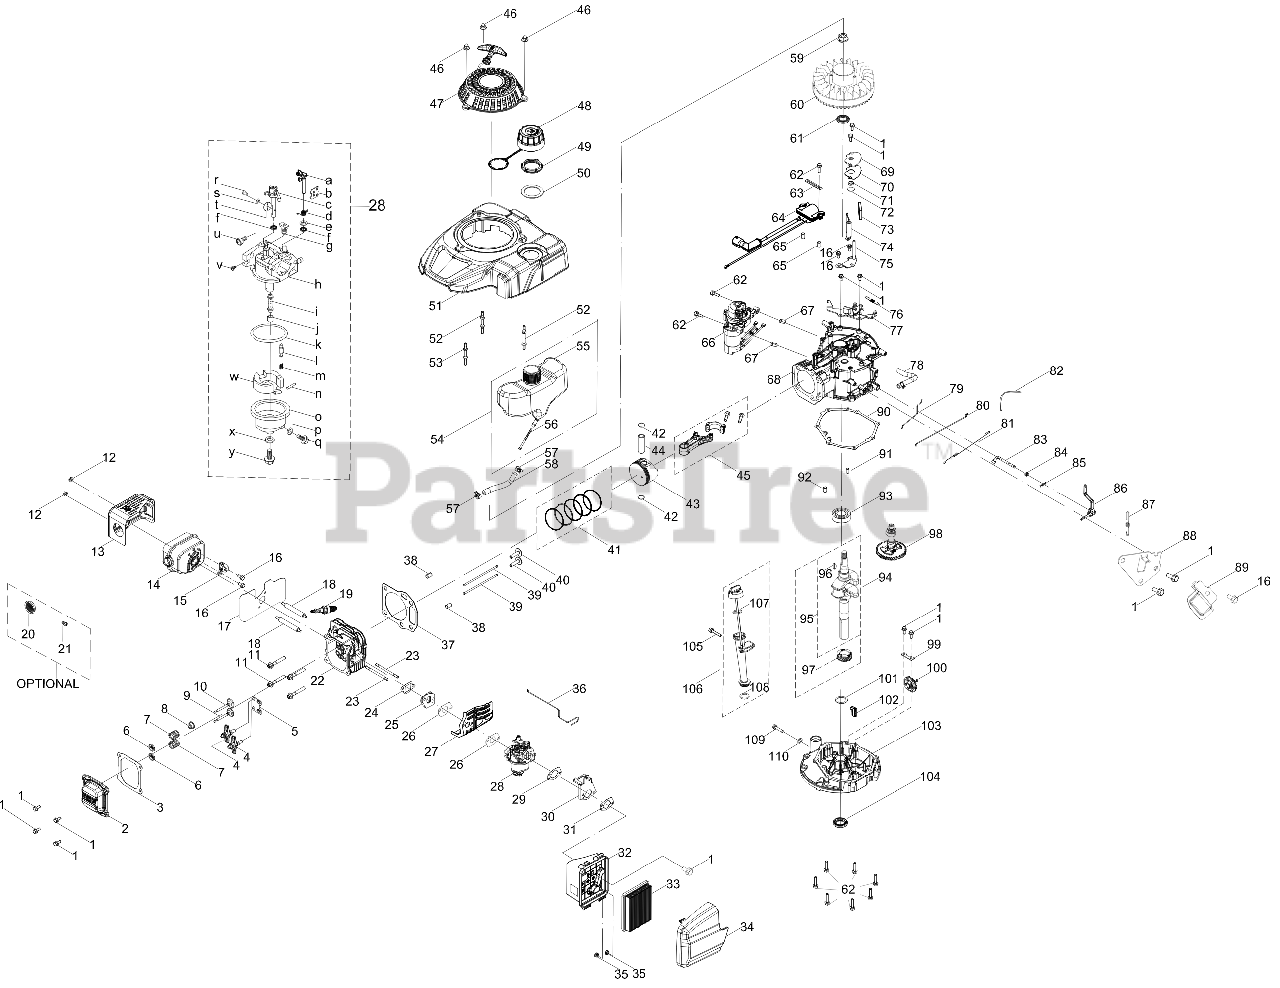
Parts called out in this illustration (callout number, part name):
1	BOLT M6-1 x 14 GR8.8
2	VALVE COVER
3	VALVE COVER GASKET
4	ROCKER ARM ASSEMBLY
5	PUSH ROD GUIDE
6	VALVE SPRING RETAINER
7	VALVE SPRING
8	INTAKE VALVE SEAL
9	EXHAUST VALVE
10	INTAKE VALVE
11	BOLT-M8 x 54
12	HEX NUT
13	MUFFLER SHIELD
14	MUFFLER ASSEMBLY
15	THERMOSTAT
16	BOLT M6-1 x 12 GR8.8
17	MUFFLER GASKET
18	STUD M6-1 x 95
19	SPARK PLUG
20	SPARK ARRESTOR
21	SCREW M3.5 x 9.5
22	CYLINDER HEAD
23	STUD M6 x 90
24	CARBURETOR INSULATOR GASKET
25	CARBURETOR INSULATOR
26	CARBURETOR GASKET
27	CARBURETOR HEAT SHIELD
28	CARBURETOR
29	AIR FILTER BRACKET GASKET
30	AIR FILTER BRACKET
31	AIR FILTER BASE GASKET
32	AIR FILTER BASE
33	AIR FILTER
33	Cub Cadet AIR FILTER
33	Genuine Factory Parts AIR FILTER
34	AIR FILTER COVER
35	HEX NUT
36	CHOKE TEMP CONTROL LINKAGE
37	CYLINDER HEAD GASKET
38	DOWEL PIN
39	PUSH ROD
40	TAPPET
41	PISTON RING SET
42	SNAP RING-PISTON PIN
43	PISTON
44	PISTON PIN
45	CONNECTING ROD ASSEMBLY
46	ACORN NUT
47	RECOIL STARTER ASSEMBLY
48	FUEL CAP W/TETHER
49	FUEL TANK NUT
50	FUEL TANK UPPER GROMMET
51	ENGINE SHROUD W/O IGNITION SWITCH
52	STARTER/SHROUD REAR STUD
53	STARTER SHROUD FRONT STUD M6X74
54	FUEL TANK ASSEMBLY
55	FUEL TANK
56	FUEL FILTER
56	Genuine Factory Parts FUEL FILTER
57	HOSE CLAMP
58	FUEL HOSE
59	FLYWHEEL NUT
60	FLYWHEEL ASSEMBLY
61	CRANKSHAFT SEAL
62	BOLT-M6-1 x 28 GR8.8
63	FLEXIBLE CLAMP
64	IGNITION COIL ASSEMBLY
65	IGNITION COIL SPACER
66	ELECTRIC STARTER ASSEMBLY
67	DOWEL PIN
68	CRANKCASE
69	BREATHER COVER PLATE
70	BREATHER GASKET
71	BREATHER VALVE SPRING
72	BREATHER VALVE
73	BREATHER SCREEN
74	AIR VANE
75	AIR VANE BRACKET
76	ENGINE BRAKE SPRING
77	ENGINE BRAKE ASSEMBLY
78	BREATHER HOSE ASSEMBLY
79	CHOKE LINKAGE
80	THROTTLE LINKAGE
81	THROTTLE LINKAGE SPRING
82	CABLE TIE - 3 x 150
83	GOVERNOR ARM SHAFT
84	GOVERNOR SEAL
85	COTTER PIN
86	GOVERNOR ARM ASSEMBLY
87	GOVERNOR SPRING
88	COMPONENT BRACKET
89	GOVERNOR SHIELD
90	CRANKCASE COVER GASKET
91	DOWEL PIN
92	DOWEL PIN
93	BEARING
94	CRANKSHAFT ASSEMBLY
95	CRANKSHAFT
96	FLYWHEEL KEY
97	CRANKSHAFT TIMING GEAR
98	CAMSHAFT ASSEMBLY
99	GOVERNOR GEAR MOUNTING PLATE
100	GOVERNOR GEAR/SHAFT ASSEMBLY
101	THRUST WASHER
102	OIL RETURN SEAL
103	CRANKCASE COVER
104	LOWER CRANKSHAFT SEAL
105	BOLT M6-1 x 35 GR8.8
106	OIL DIPSTICK ASSEMBLY
107	O-RING
108	O-RING
109	OIL DRAIN PLUG
110	WASHER
S	Throttle Plate Lock Washer
